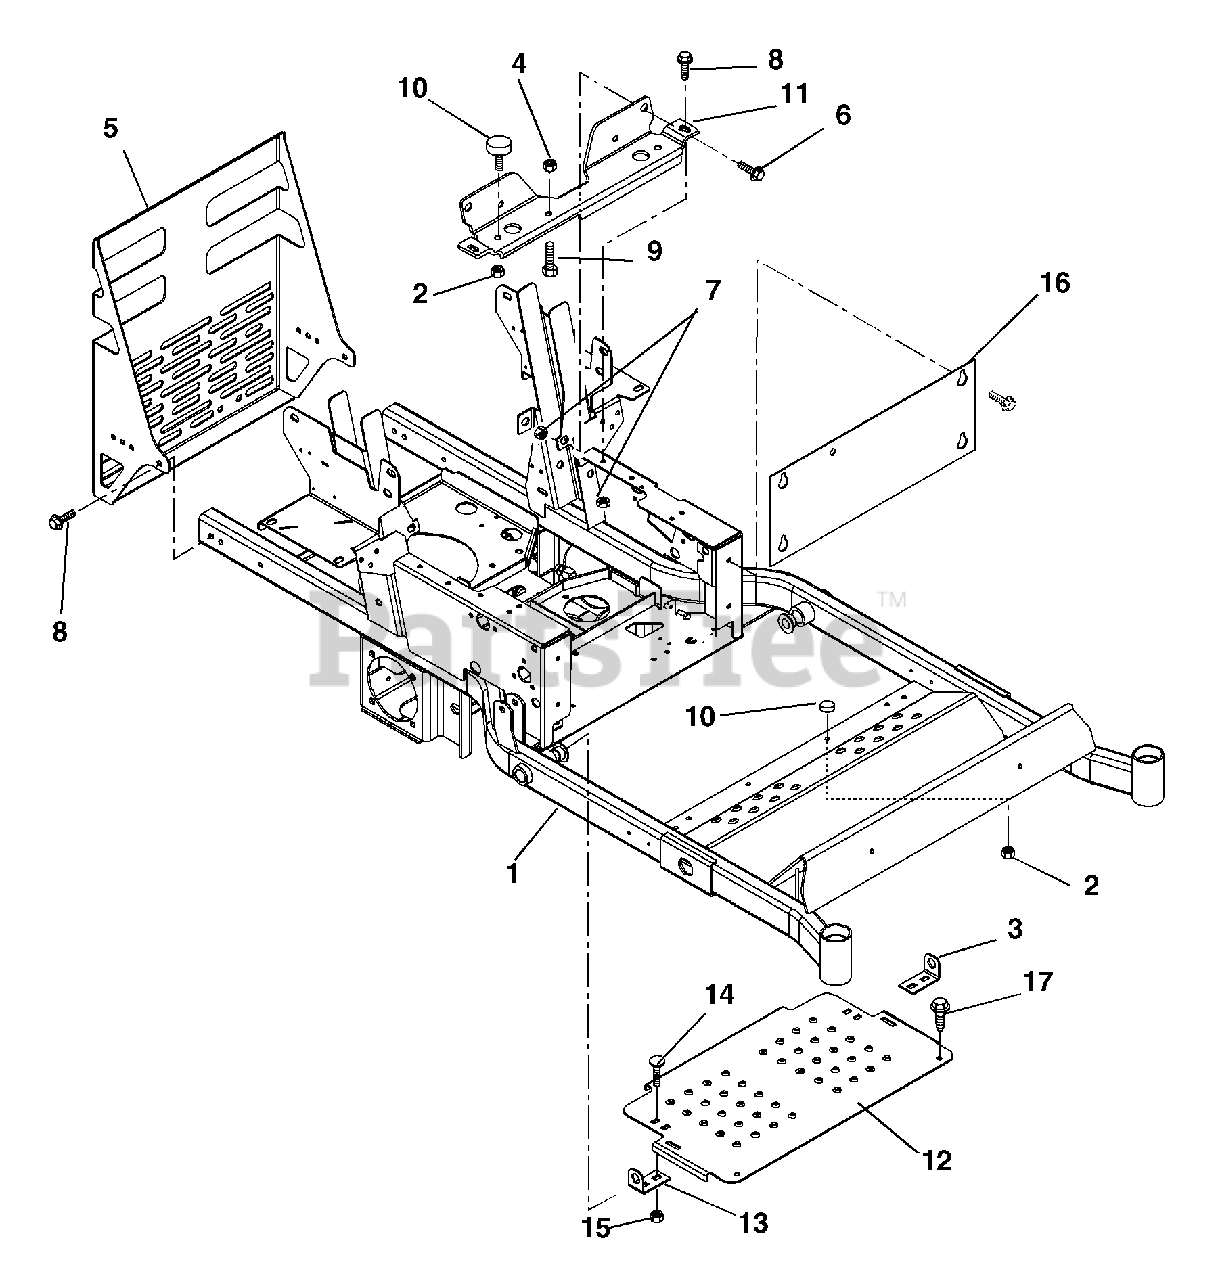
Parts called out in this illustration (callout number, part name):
1	Intermediate Z Frame (042, 043, 044)
1	Intermediate Z Frame (051)
2	Nut-Spin Lock-Flange .312-18
3	Hinge, Footboard Left Hand
4	Nut-Locking-Top-Flange .31-18
5	Bumper/Guard
6	Bolt-Serrated Flange Washer Head .38-16 x 1.00
7	Nut-Retainer .375-16 x .37
8	Screw-Tapping .38-16 x .50 Hex Washer Head
9	Bolt-Hex .31-18 x 1.25 Grade 5
10	Bumper, Rubber
11	Seat Support
12	Footrest Panel
13	Hinge, Footboard Right Hand
14	Bolt-Round Head Square Neck .38-16 x .75 Grade 5
15	Nut-Locking-Top-Flange .38-16
16	Access Panel
17	Screw-Tapping .38-16 x 1.00 Hex Washer Head (310, 311)
